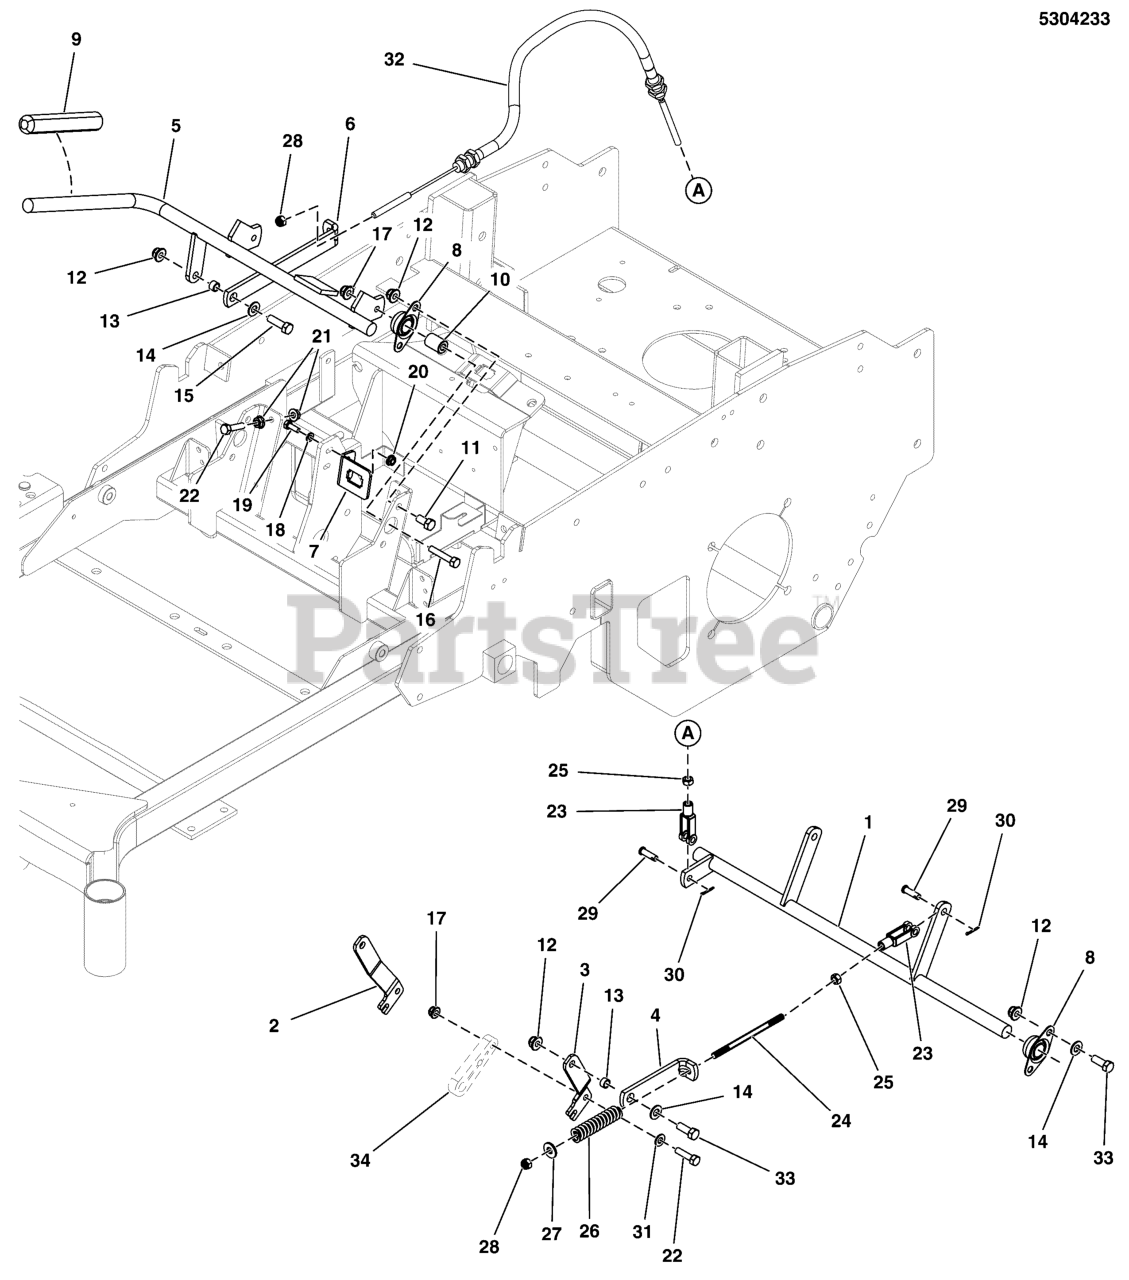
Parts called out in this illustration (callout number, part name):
1	WELD, BRAKE SHAFT, 150XT - BLK
2	PLATE, RIGHT BRAKE, 150XT - BLK
3	PLATE, LEFT BRAKE, 150XT - BLK
4	LINK, BRAKE LOCK, 150XT - BLK
5	WELD, BRAKE SHAFT - BLK
6	LINK, BRAKE LOCK - BLK
7	BRACKET, SWITCH MOUNT - BLK
8	BEARING, BRONZE FLANGE, 3/4"
9	GRIP, FOAM, 3/4 ID X 6 X .187
10	SPACER, .32 X .75 X 1.06, PM
11	BOLT, 3/8-16 X 3/4" GD5 CZ
12	NUT, 3/8 - 16 HEX NYLOCK FLANGE
13	SPACER, .38 X .50 X .31, CZ
14	WASHER, 3/8 SAE
15	BOLT, 3/8-16 X 1-1/4" GD5 CZ
16	BOLT, 5/16-18 X 1-3/4" GD5 YZ
17	NUT, 5/16-18 HEX NYLOCK FLANGE NUT
18	WASHER, 1/4 SAE
19	BOLT, 1/4"-20 X 3/4" GD5 YZ
20	NUT, 1/4-20 HEX SERR. FLANGE
21	NUT, 5/16-18 HEX SERRATED FLANGE (SMALL)
22	BOLT, 5/16-18 X 1-1/4" GD5 YZ
23	CLEVIS, 5/16-24, STEEL, CLEAR ZINC
24	ROD, BRAKE PULL, S150XT
25	NUT, Hex, 5/16-24
26	SPRING, COMP. 1/2 ID X .140 WIRE X 3.25
27	WASHER, 5/16" USS
28	NUT, 5/16-24 HEX NYLON LOCK
29	PIN, CLEVIS, 5/16 X 1, PLATED
30	PIN, 3/32 X 0.750, COT, ZINC/CLEAR
31	WASHER, 5/16" SAE
32	CABLE, PARKING BRAKE IS2000
33	BOLT, 3/8-16 X 1" GD5 CZ
34	Refer to: Hydraulic Group
